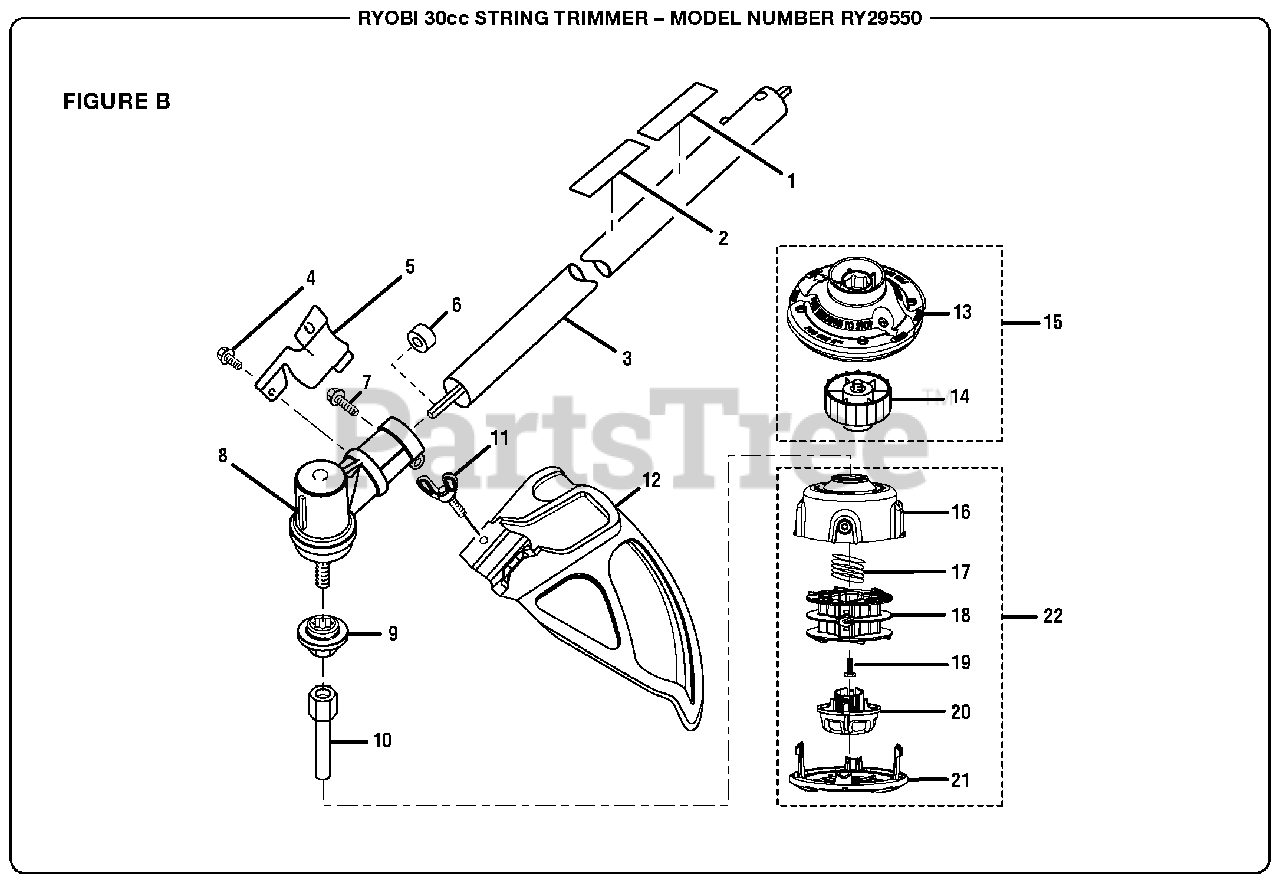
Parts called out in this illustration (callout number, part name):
1	Expand-it Label
2	Warning Decal
3	Straight Shaft Assembly
4	Screw (10-24 x 5/8 in.)
5	Clamp
7	Screw (1/4-20 x 1-1/4 in.)
8	Gear Head
9	Flanged Washer
11	Wing Screw (1/4-20 x 1-1/4 in.)
12	Grass Deflector Assembly
13	Pro Cut II String Head
14	Spool Retainer (Red)
15	Pro Cut II String Head Assembly (Inc. Key Nos. 13-14)
16	Housing (Inc. Key No. 21)
19	Bolt (5/16-18 x 1/2 in. LH)
22	Reel Easy String Head Assembly (Inc. Key Nos. 16-21)
